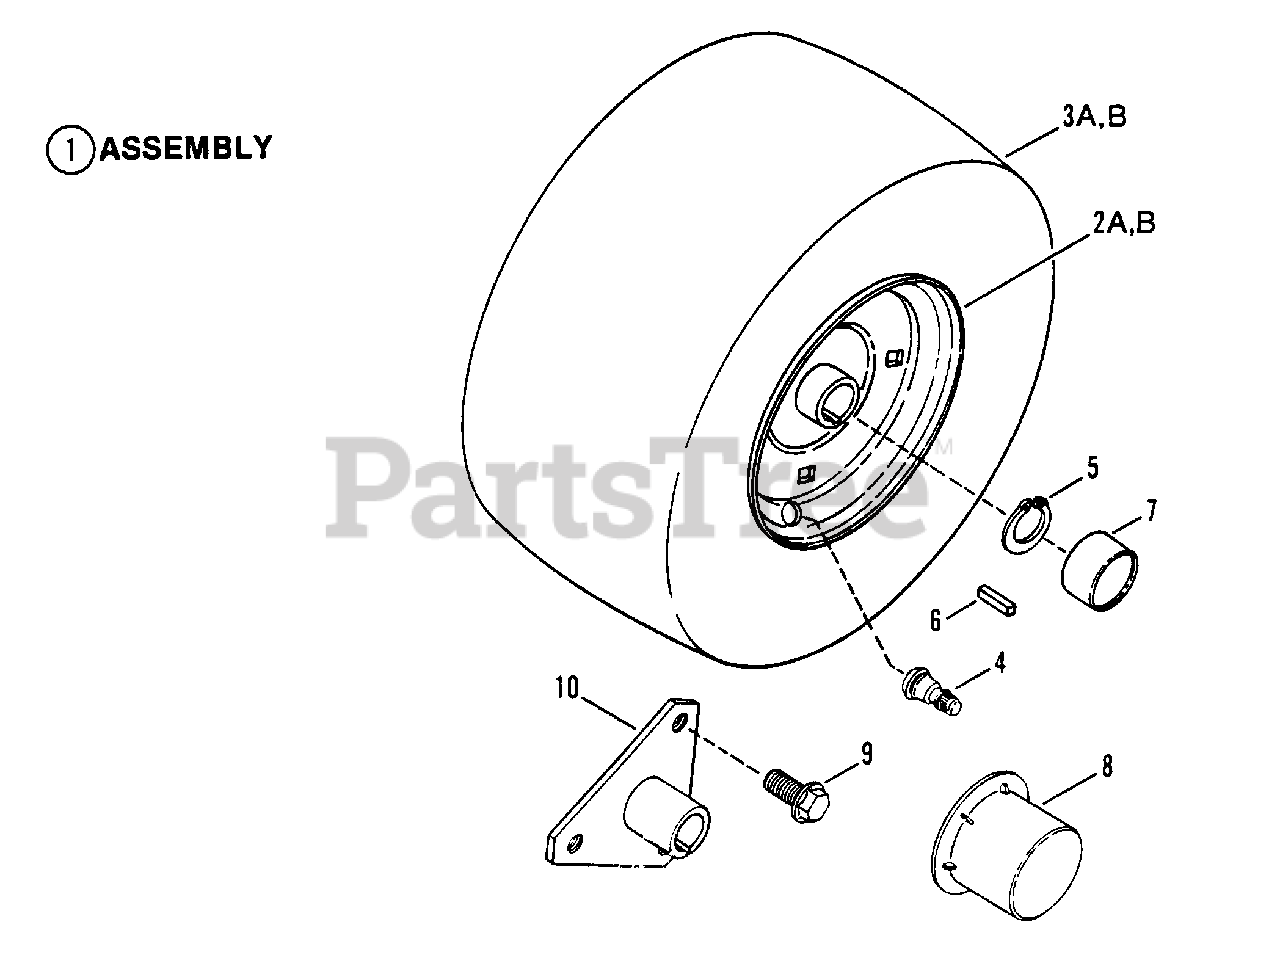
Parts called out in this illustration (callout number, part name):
1	ASSEMBLY, Rear Tire & Rim
2A	RIM, 10 x 5
2B	RIM, 12 x 9
3A	TIRE, 21 x 7.00 x 10
3B	TIRE, 23 x 10.50 x 12
4	VALVE, Air
5	RING, Retaining
6	KEY, 1/4 x 1/4 x 2" Square
7	COVER, Dust
8	HUB-CAP
9	BOLT, 1/2-20 x 3/4" Lug
10	HUB, Rear Wheel
